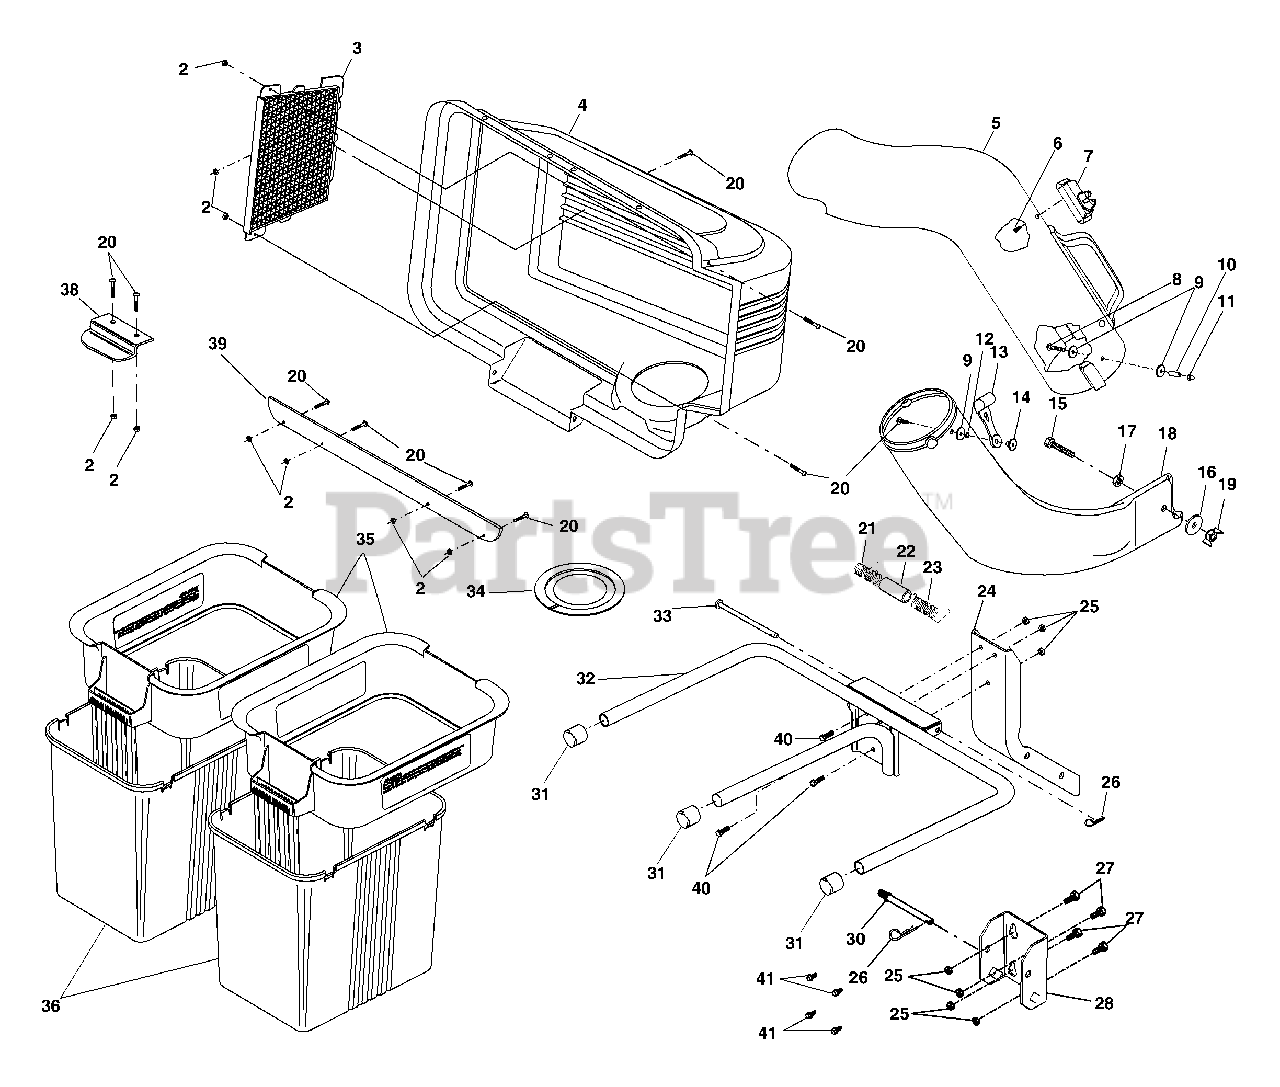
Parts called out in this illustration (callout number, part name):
2	Nut, Crownlock #10-24
3	Screen, Cover
4	Cover Asm.
6	Screw, Special
7	Dump Bag Indicator
8	Screw, #10-24 x 1-1/8
9	Washer 3/16x3/4x16 Ga.
10	Spacer, Split
11	Nut, Acorn #10-24
14	Nut, Weld
15	Bolt, Hex 3/8-16 x 1-1/4
16	Washer 13/32x1 x 16 Ga.
17	Locknut 3/8-16
19	Wingnut 3/8-16
20	Screw #10-24 x 5/8
21	Spring, Cover L.H. (black)
22	Spacer, Cover
23	Spring, Cover R.H. (gray)
24	Post, Support
25	Locknut 5/16 x 18
26	Spring, Retainer
27	Bolt, Hex 5/16-18 x 3/4
28	Bracket, Mounting
30	Pin, Support Post
31	Plug, Tubing End
32	Bagger, Frame
33	Pin, Hinge
34	Gasket, Cover
35	Container, Top
36	Container, Bottom
38	Latch Handle, Cover
39	Strip, Reinforcement
40	Carriage Bolt 5/16-18 x 3/4
41	Shoulder Bolt Hex, Self Tapping
